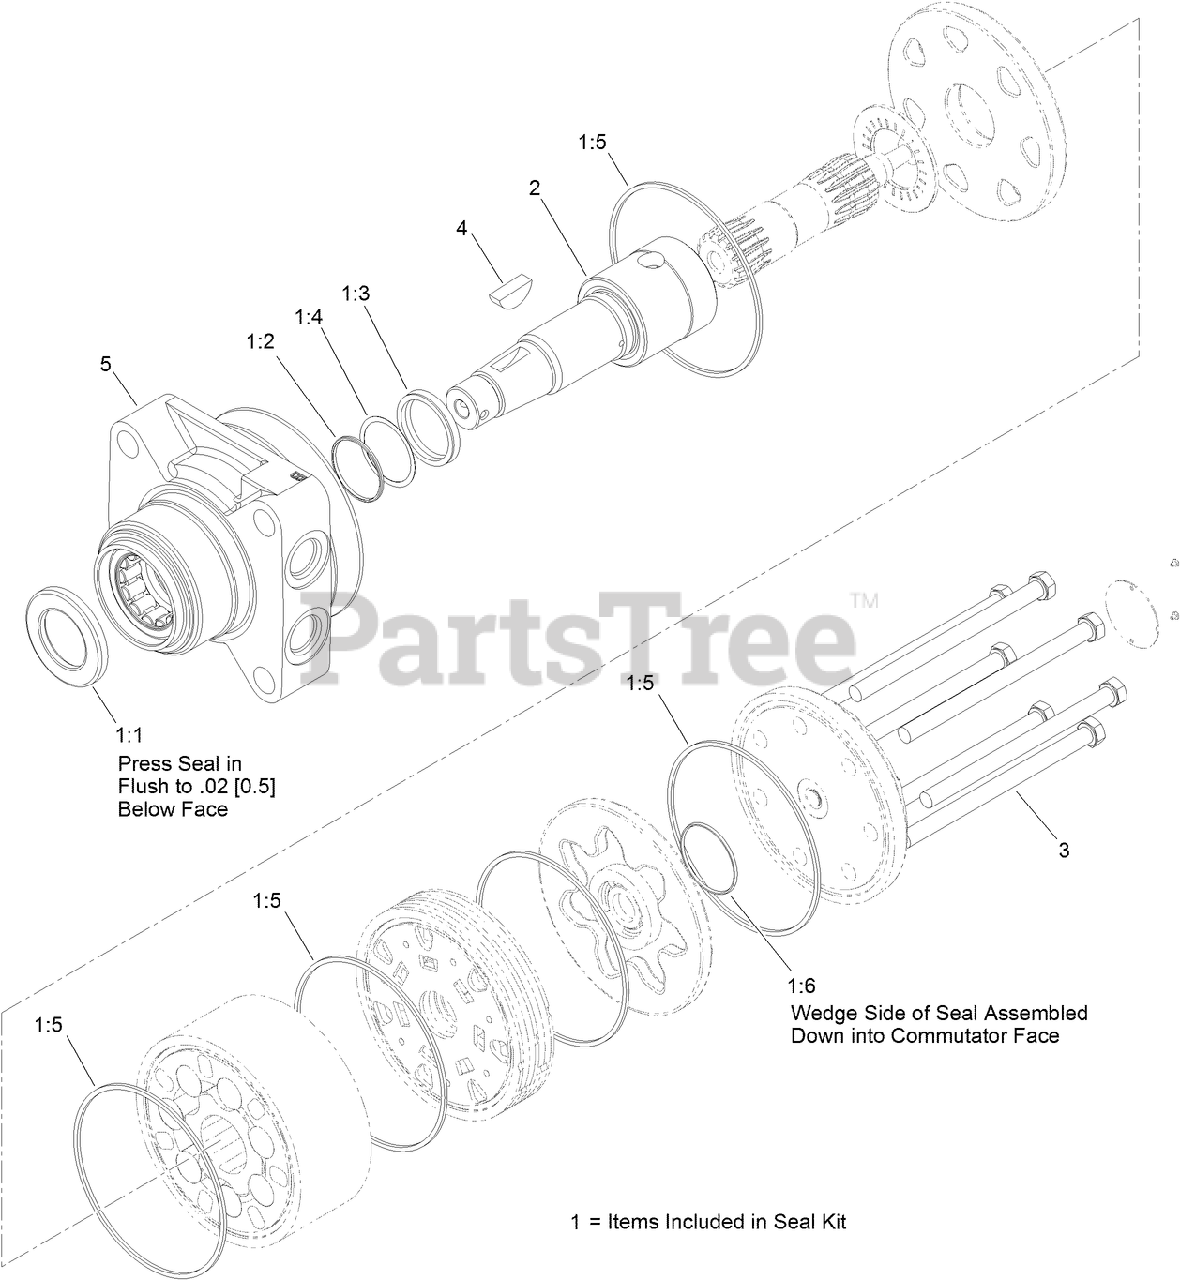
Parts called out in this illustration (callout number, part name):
1	SEAL KIT
1:1	Seal-Dirt and Water
1:2	BACKUP-RING
1:3	SEAL-SHAFT
1:4	Washer-Backup
1:5	SEAL-SQUARE, RING (INNER)
1:6	Seal-Commutator
2	SHAFT-COUPLING
3	SCREW-CAP, HH
4	KEY-WOODRUFF
5	MOTOR HOUSING ASM
